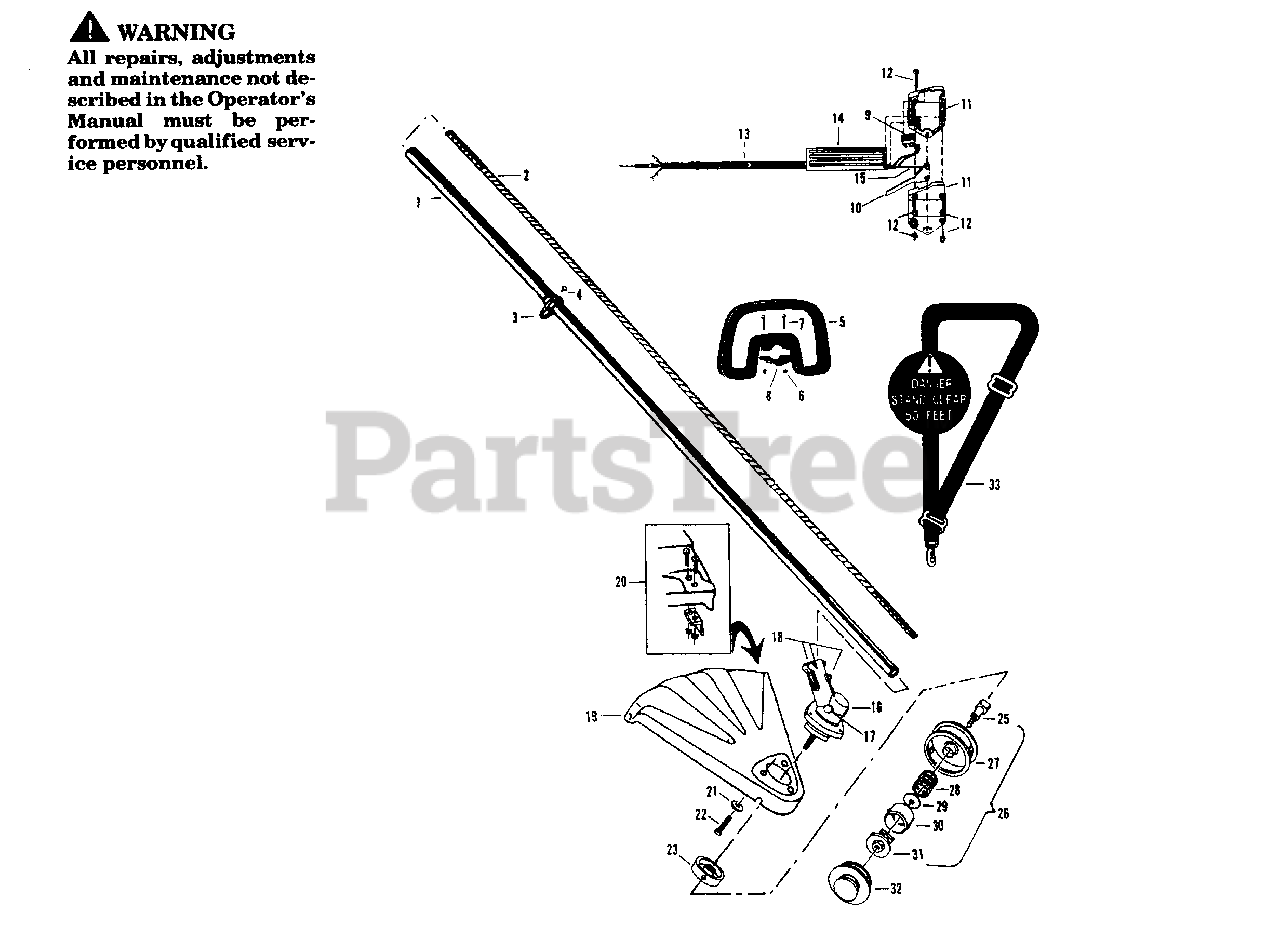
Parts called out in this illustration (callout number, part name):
1	Drive Shaft Housing
2	Flexible Shaft
3	Swivel Assembly (Incl. 4)
4	Thumb Screw
5	Tear Drop Handle (Incl. 6-8)
9	MODELS PPC22/PPC25
9	MODEL PPC31
10	Trigger
11	R.H. & L.H. Housing
12	Screws, Throttle Housing
13	Cable & Wire Cover
15	Throttle Cable
16	Gear Head Complete
17	Grease Plug
18	Clamp and Screw Set
19	Shield w/ Line Limiter
20	Line Limiter Kit
23	Cup Washer
24	Two-Line Cutting Head (Incl. 25, 27-32)
25	Shaft, Bolt, L.H.
26	Housing Assembly (Incl. 25-31)
27	Housing
30	Outer Drive
31	Inner Cam
33	Shoulder Strap
